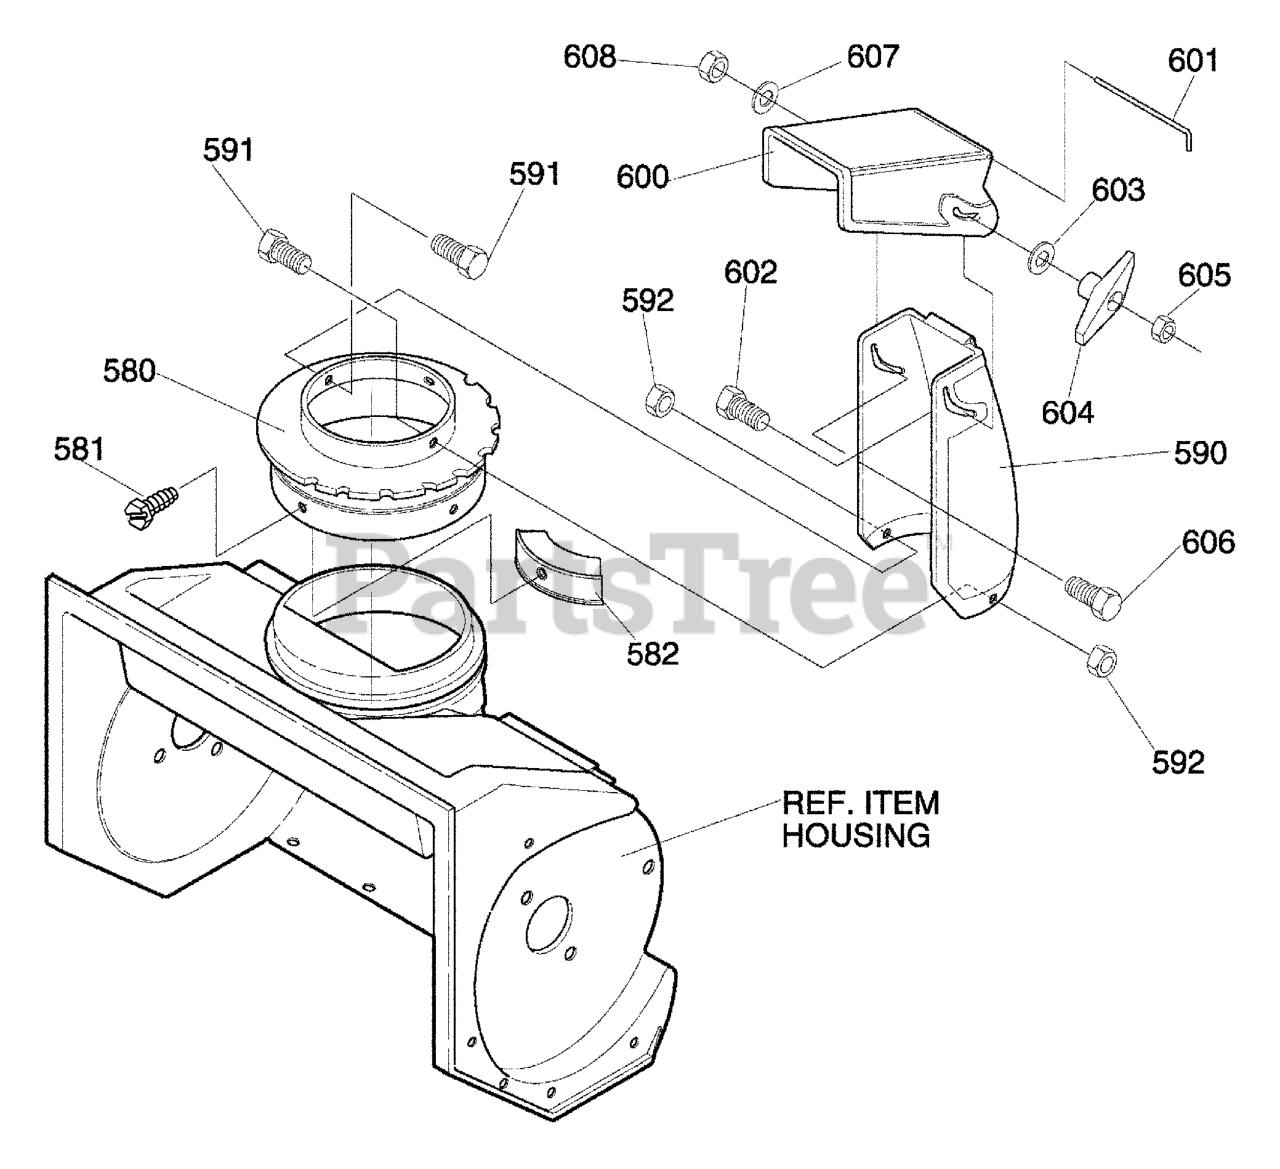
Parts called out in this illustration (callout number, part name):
580	RING, CHUTE
581	SCREW, #10X.50
582	GUIDE, CHUTE
590	CHUTE, LOWER
591	SCREW 1/4-20X.50
592	NUT, 1/4-2 YZ
600	CHUTE, UPPER
601	WIRE, HINGE
602	BOLT, CARRIAGE 5/16-18X1.25
603	WASHER, FLAT .349X.69X.066
604	KNOB, T
605	NUT, HEX 5/16-18
606	SCREW, 5/16-18 x 0.75
607	WASHER, FLAT .349X.69X.066
608	NUT, HEX 5/16-18
